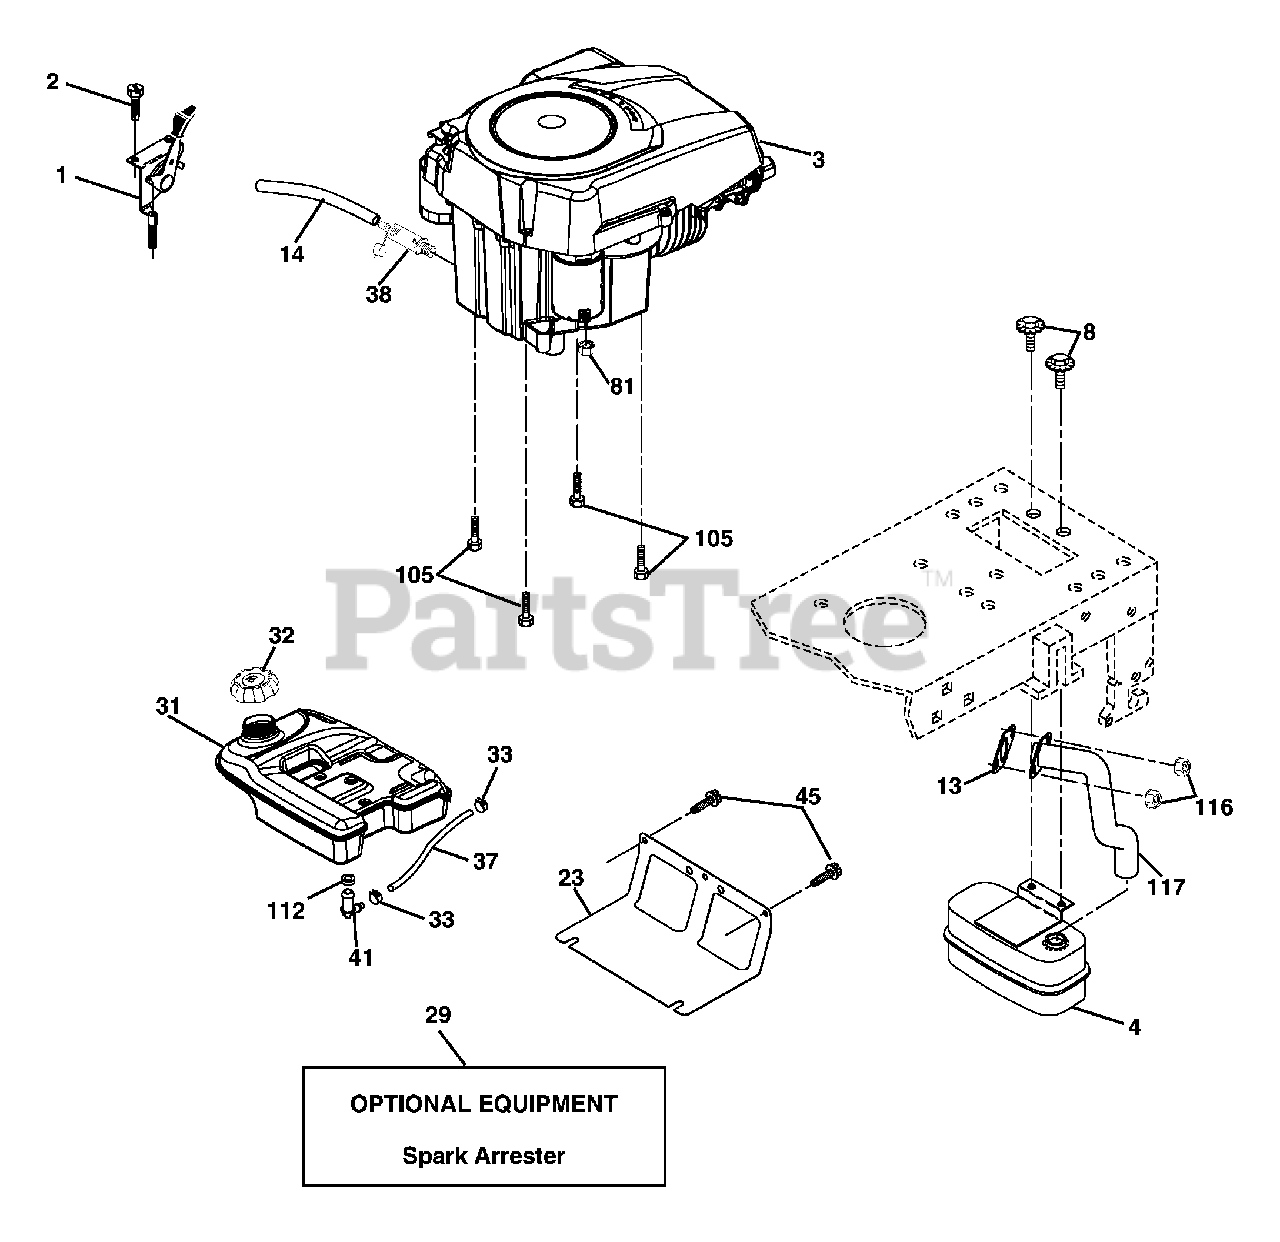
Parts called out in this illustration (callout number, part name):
1	Control, Throttle / Choke
2	Screw 10 x 3/4 Single Lead Hex
4	Muffler
8	Bolt 5/16-18 unc x 3/4 w/Sems
13	Muffler Gasket
14	Tube Oil Drain
23	Shield, Browning / Debris Guard
29	Arrester, Spark
31	Tank, Fuel
32	Cap Gauge, Fuel
33	Clamp, Hose Blk
37	Line, Fuel
38	Plug Drain Oil Easy
41	Stem Tank Fuel
45	Screw Hex Wsh Thdrol 3/8-16 x 3/4
81	Nut Keps Hex 1/4-20 UNC
105	Screw 3/8-16 x 1
112	Bushing
116	Nut Hex Flange Toplock M8-1.25
117	Tube Exhaust
